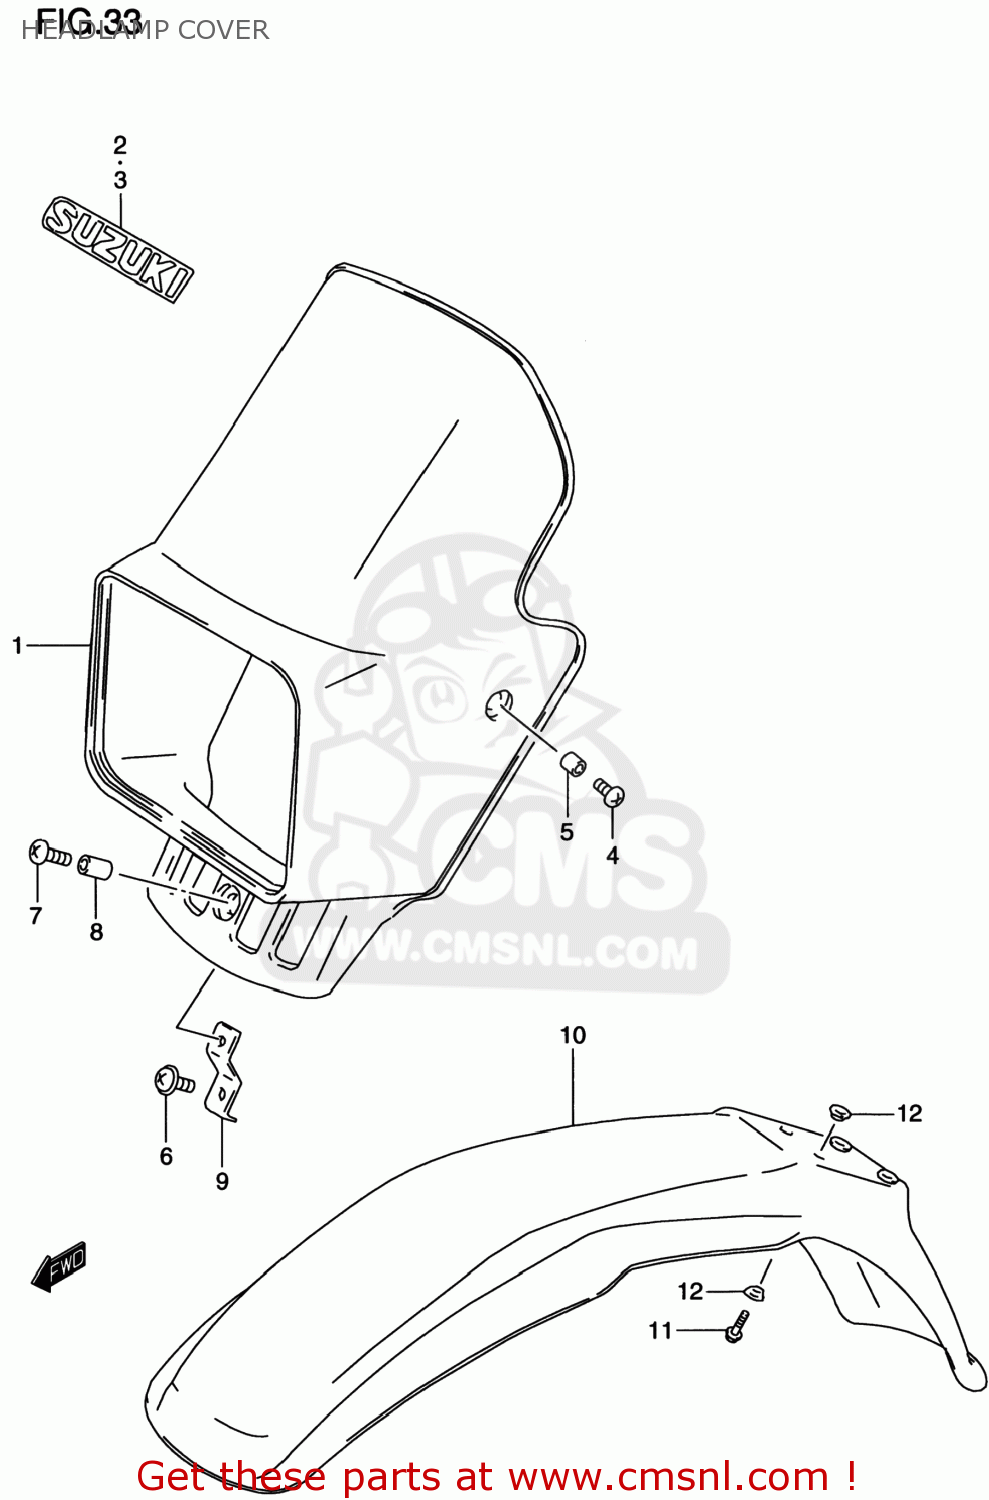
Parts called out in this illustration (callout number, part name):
1	COVER,HEADLAMP
2	EMBLEM,HEADLAMP COVER
3	EMBLEM
4	SCREW 6X12
5	SPACER(6.1X8X3.5)
6	SCREW
7	SCREW
8	SPACER(6.1X8X12)
9	BRACE,HEADLAMP HOUSING LWR
10	FENDER,FR
11	BOLT
12	WASHER
